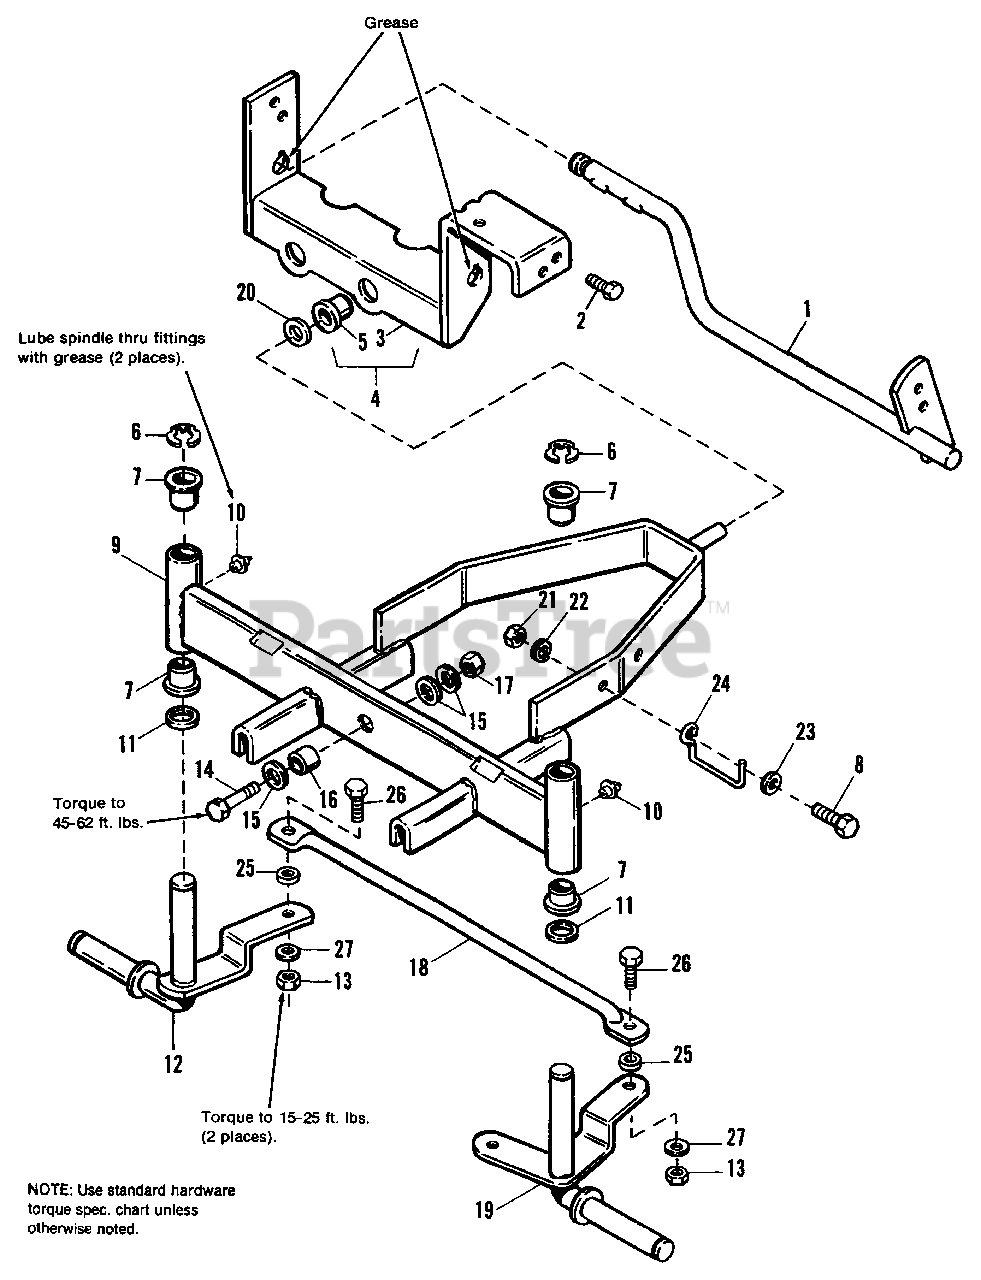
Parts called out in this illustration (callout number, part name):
1	LEVER ASSY., Brake
2	SCREW, Taptite, 5/16-18 x 3/4
4	SUPPORT ASSY., Rear (Incl. Ref. No. 3 & 5)
6	KLIPRING, Ext. 3/4
8	CAPSCREW, Hex, 5/16-18 x 1
9	AXLE ASSY., Front (Incl. Ref. No. 7)
10	FITTING, Grease, Drive, Type
11	WASHER
12	SPINDLE ASSY., R.H.
13	LOCKNUT, Hex, 3/8-16
14	CAPSCREW, Hex, 1/2-13 x 1-3/4
15	WASHER, 9/16
16	SPACER
17	LOCKNUT, Hex, 1/2-13
19	SPINDLE ASSY., L.H.
20	WASHER, 5/8
21	NUT, Hex, 5/16-18
22	LOCKWASHER, 5/16 (Used on models 1691033, 1691234 & 1691235 only.)
23	WASHER, 5/16
24	GUIDE, Drag Link
25	SPACER, Tie Rod
26	CAPSCREW, 3/8-16 x 1
27	WASHER
